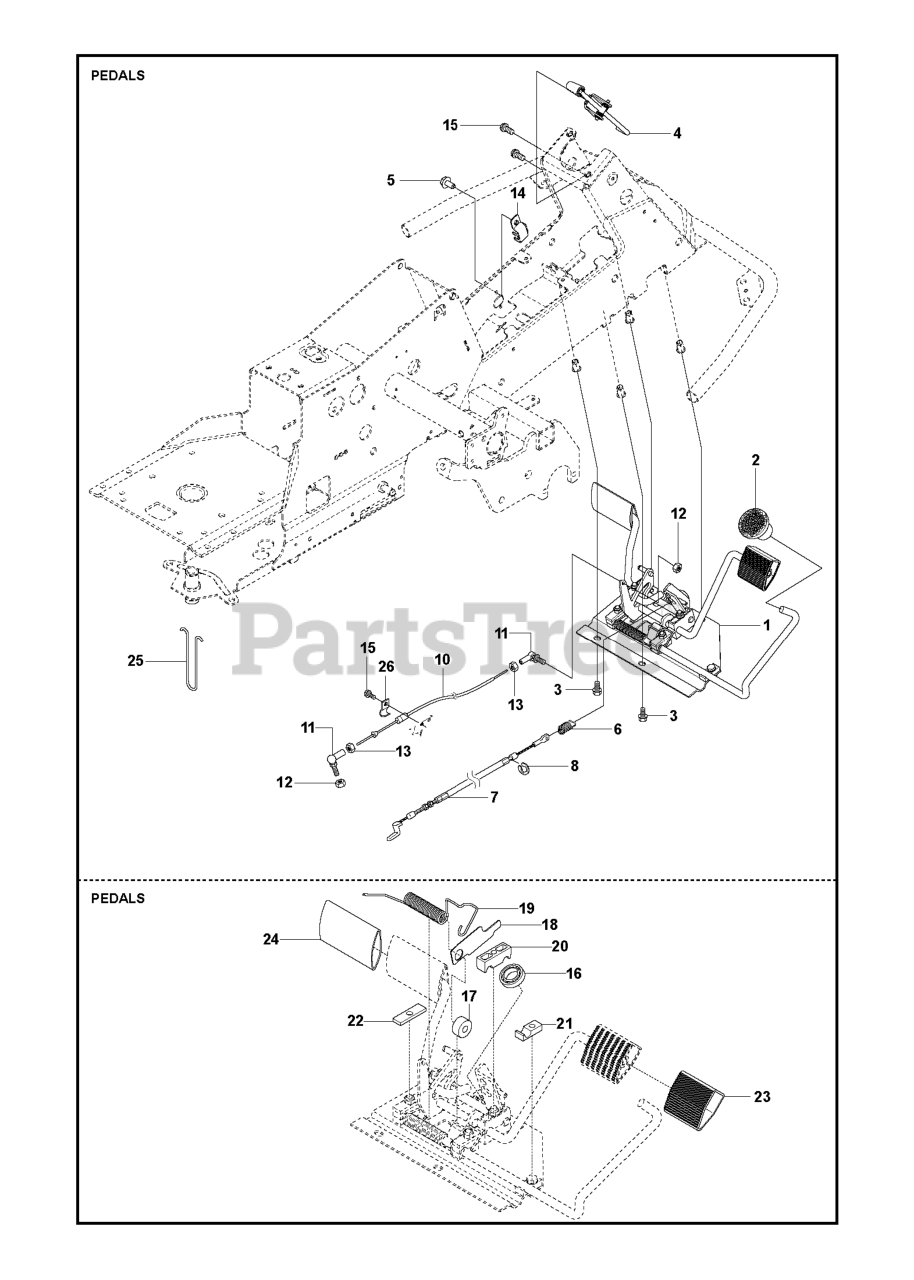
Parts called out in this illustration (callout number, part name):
2	KNOB, THREADED
4	BRAKE LEVER ASSY
5	SCREW EHHFM
7	BRAKE WIRE
10	CONTROL CABLE
11	CONNECTOR, BALL JOINT
12	LOCKNUT M6
16	BALL BEARING 6002-2RS1
17	ROLLER
18	PLATE
19	SPRING
20	PEDAL SHAFT CLAMP
21	SUPPORT
22	PLATE
23	PEDAL RUBBER
24	PEDAL RUBBER L = 102MM
25	CABLE HOLDER
